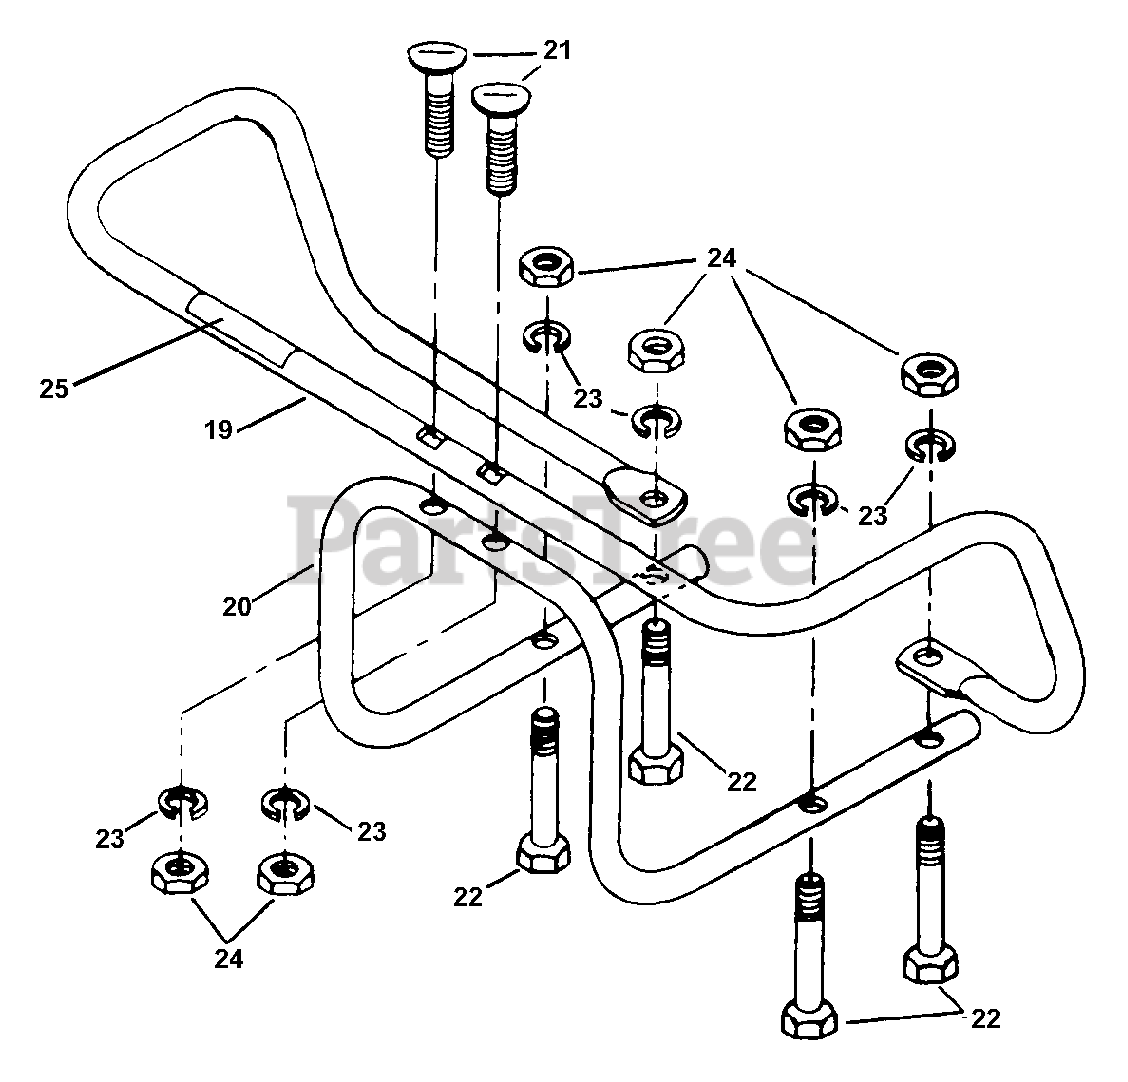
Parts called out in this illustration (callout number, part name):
19	Bumper, top section
20	Bumper, bottom section
21	Bolt-curved head, 5/16-18 x 2" (special bolt)
22	Bolt, hex hd., 5/16"-18 x 2- 1/2"
23	Lockwasher, 5/16"
24	Nut-hex., 5/16"-18
25	Decal-caution
